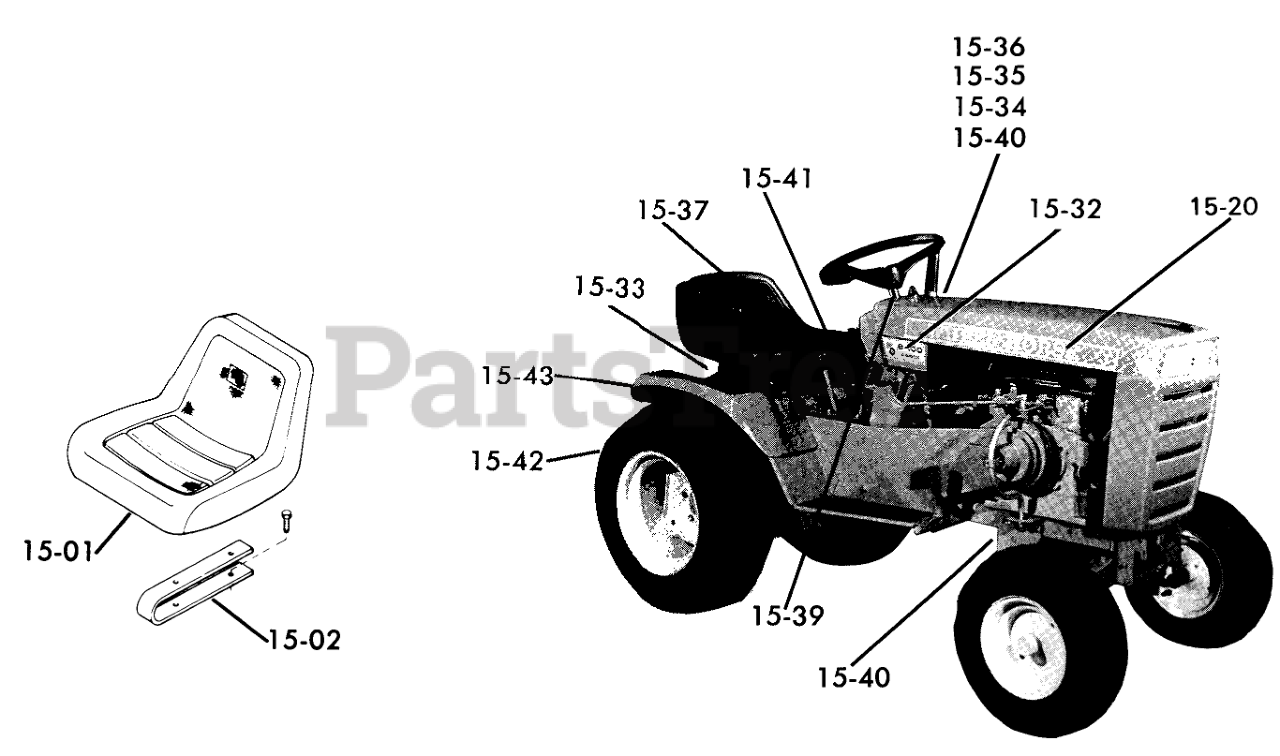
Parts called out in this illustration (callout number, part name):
15-01	Seat
15-02	Seat Spring
15-20	Decal
15-32	Decal-C-160
15-33	DECAL-WHEEL HORSE
15-34	Decal-Caution
15-35	Decal-Read Manual
15-36	DECAL-HAND LIFT
15-37	DECAL-4 SPD SHIFT
15-38	Decal-Park Brake
15-39	Decal
15-40	Decal-Tach-a-matic
15-41	DecaI-Hi-Lo
15-42	Decal-Unidrive
15-43	Reflector
